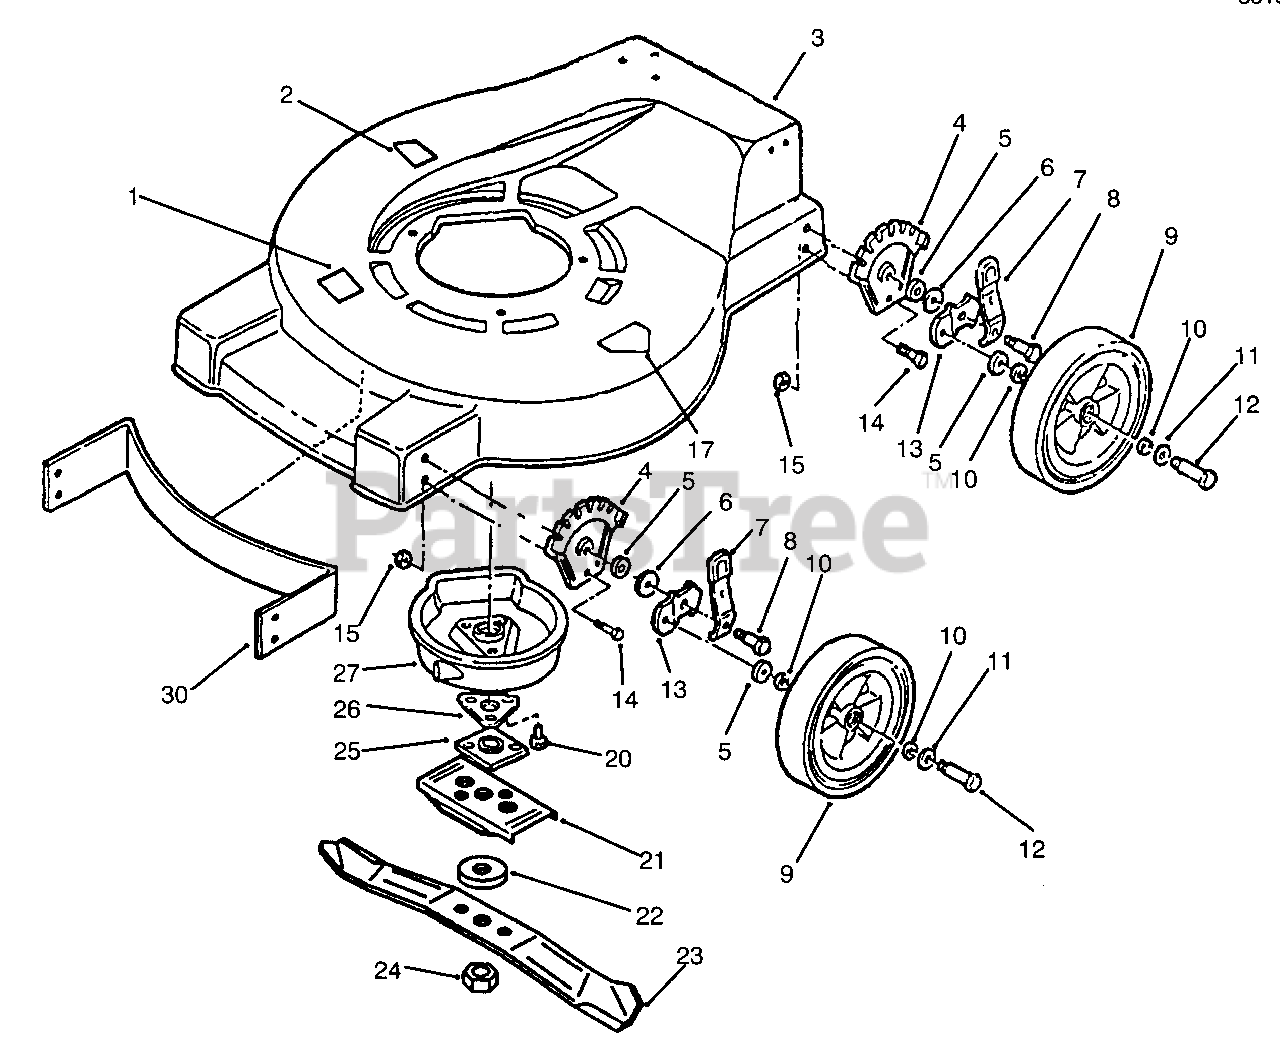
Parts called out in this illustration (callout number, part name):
1	Decal-Sound Emission
2	Decal-Spark Plug
3	Assembly-Housing (Incl. Ref. #15, 17, 30, & #22 on next page.)
4	Plate-Height Adjustment
6	Washer-Height Adj. Plate
7	Knob & Spring
8	Bolt-Shoulder
9	Assembly-Tire & Wheel (Incl. Ref. #10-11)
10	Washer-Felt
11	Washer-Wheel Bolt
12	Bolt-Shoulder, Wheel
13	Bracket-Height Adjust.
14	Screw-Height Adj. Bracket
15	Nut-Hex.
17	Decal-Blade Warning
20	Screw-Crankshaft Stiffener
21	Stiffener-Blade
23	Blade-20"
24	Nut-Lock
25	Plate & Collar
26	Support-Crankshaft
27	Cover-Muffler
30	Baffle-Front
